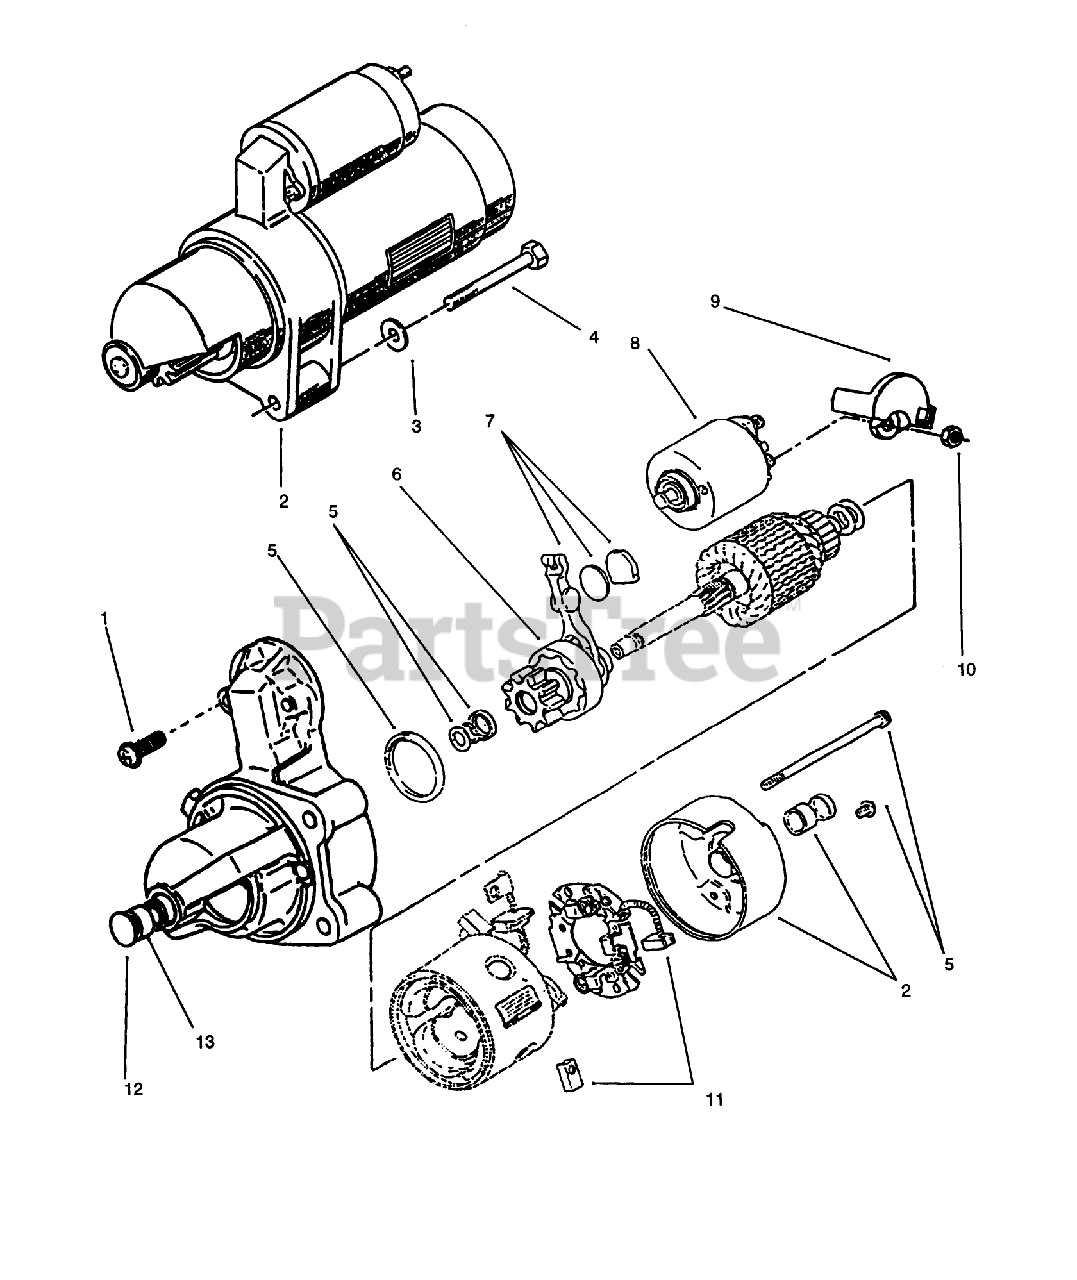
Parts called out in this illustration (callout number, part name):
3	WASHER
12	BUSHING
13	KIT-MTG BRKT
